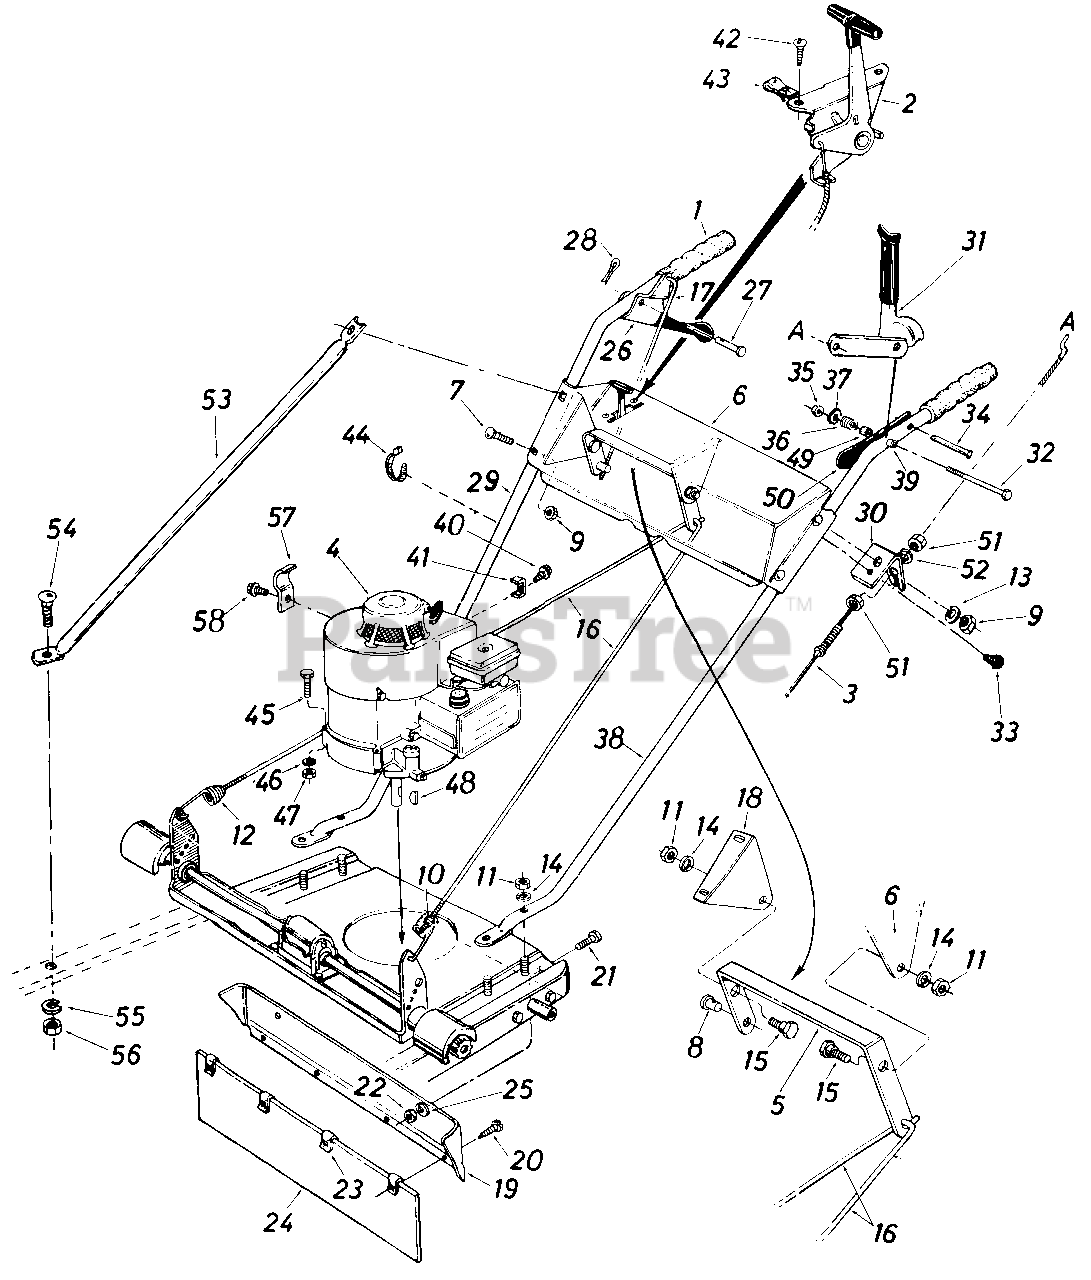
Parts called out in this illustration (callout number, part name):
1	Grip B I ack
2	Throttle Control Ass'y. Comp.
3	Clutch Cable 56" Long
4	Engine
5	Link Bracket
6	Hand le Panel Ass'y.
7	Carriage Bolt 5/16-18 x 1.75" Lg.
8	Adj. Ferrule 1/4-20 Thd.
9	Hex Nut 5/16-18 Thd.*
10	Hex Ins. L-Nut 1/4-20 Thd.
11	Hex Nut 3/8-16 Thd.
12	Extension Spring
13	L-Wash. 5/16" I.D.
14	L-Wash. 3/8" I.D.
15	Shld. Bolt .500" Dia. x .295
16	Lockout Rod
17	Rod .214" Dia. x 14.87" Lg.
18	Bracket
19	Drag Shield Adapter
20	Hex B-Tap Scr. #10 x .62" Lg.
21	Hex Bolt 1/4-28 x .62" Lg.
22	Hex Nut 1/4-28 Thd.
23	Speed Nut 10Z U-Type
24	Drag Shield 4.65" x 20.0" Lg.
25	L-Wash. 1/4" I.D.
26	Clutch Grip Ass'y.
27	Clevis Pin .375" Dia.
28	Intern. Cot. Pin 5/16" Dia.
29	R.H. Handle
30	Clutch Cable Brk't.
31	Blade Clutch Grip Ass'y.
32	Hex Bolt 1/4-20 x 2.25" Lg.
33	Hex Wash. S-Tap Scr. 1/4-20 x .50" Lg.
34	Lock Pin
35	Hex Cent. L-Nut 1/4-20 Thd.
36	Compression Spring .50" O.D. x .50" Lg.
37	Internal Tooth L-Wash.
38	L.H. Handle
39	Spacer.255" I.D.
40	Hex B-Tap Scr. #10 x .38" Lg.
41	Casir;g Clamp
42	Hex Wash. Hd. AB-Tap Scr. #10 x .50" Lg.
43	Speed Nut 10Z
44	Cable Tie Self Clinching
45	Hex Bolt 5/16-24 x 1.25" Lg.*
46	L-Wash. 5/16" I.D.
47	Hex Nut 5/16-24 Thd.
48	#6 Hi-Pro Key 5/32 x 5/8" Dia.
49	Spacer.255" I.D. x .375" O.D.
50	Lock Spring
51	Hex Jam Nut 5/16-24 Thd.
52	L-Wash. 5/16" I.D.
53	Strut
54	Carriage Bolt 5/16-18 x .62"-Lg.
55	L-Wash. 5/16" I.D.
56	Hex Nut 5/16-18 Thd.
57	Casing Clamp
58	Hex Wash-Hd. Tap Scr. #10 x .50" Lg.
